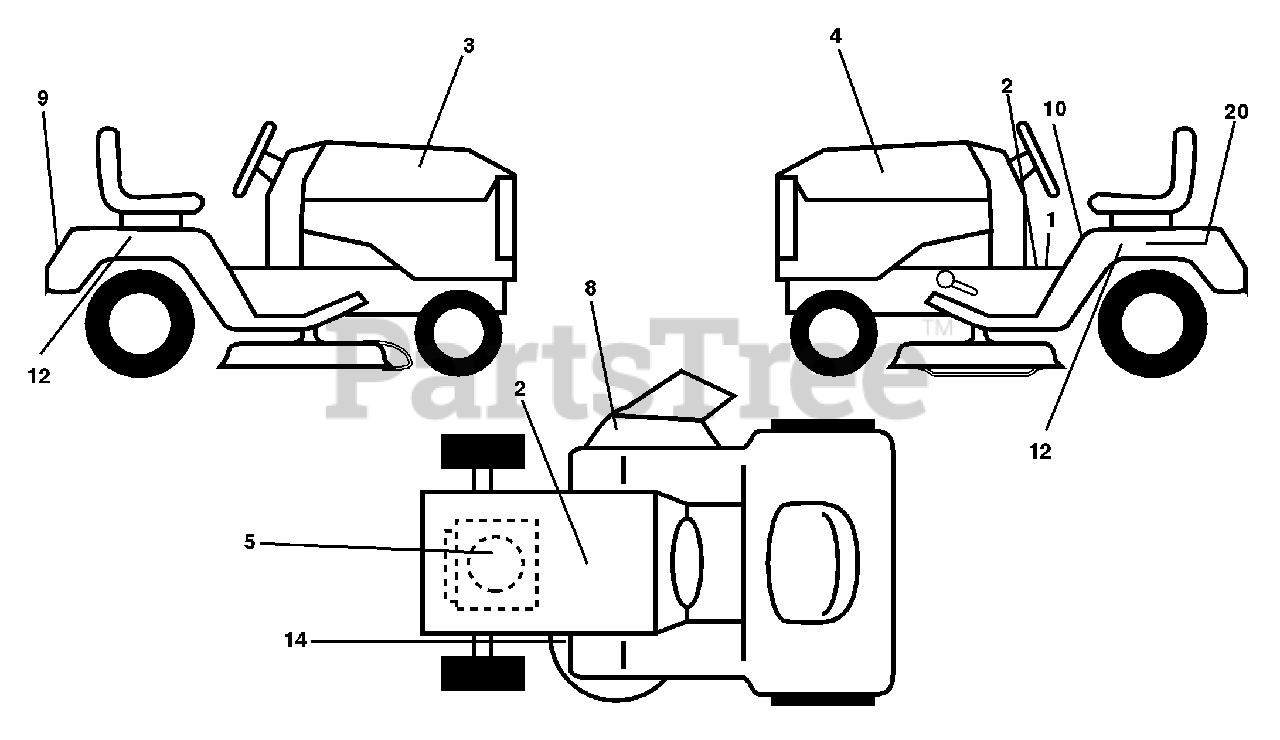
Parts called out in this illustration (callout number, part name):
1	Decal Oper. Step Thru E/F
2	Decal Battery
3	Decal Hood LH
4	Decal Hood RH
5	Decal HP Engine
8	Decal Warning Multi-Languages
9	Decal Fender Husq
10	Decal Fender Danger E/F
12	Decal Fender Auto Husq Radius
14	Decal V-Belt Schematic
